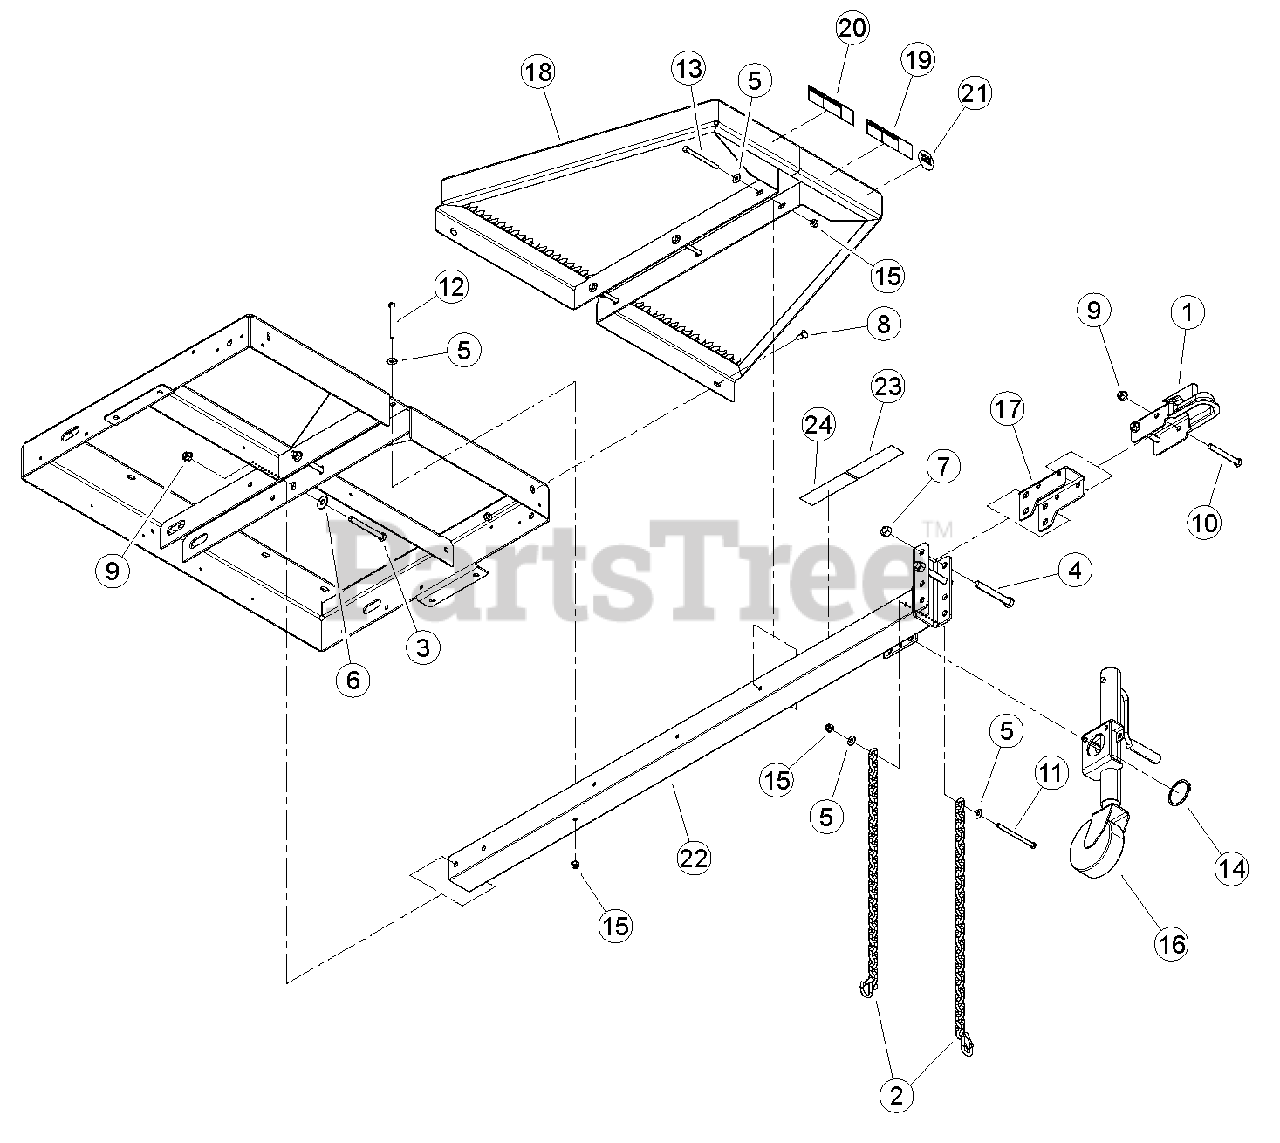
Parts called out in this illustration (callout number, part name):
1	COUPLER, 2 IN
2	CHAIN, SAFETY 5000 LB W/LATCH
3	BOLT, 1/2 X 4-1/2" GR5 HHCS NC ZP
4	BOLT, 5/8 X 4-1/2 HEX HD G5 ZP
5	WASHER, 3/8" FLAT ZP
6	WASHER, 1/2" FLAT ZP
7	NUT, 5/8" CENTERLOCK ZP GR5
8	BOLT, 3/8 X 1" GR5 CRG NC ZP
9	NUT, 1/2-13 NYLOCK FLANGE
10	BOLT, 1/2 X 4 HEX CPS G5 ZP
11	BOLT, 3/8 X 5" GR5 HEX CPS ZP
12	BOLT, 3/8 X 4" HHCS GR5 NC ZP
13	BOLT, 3/8 X 4-1/2" HHCS GR5 NC ZP
14	SNAP RING, 2-1/2 EXTERNAL
15	NUT, 3/8-16 NYLOCK FLANGE
16	JACK, PIVOTING W/ SWIVEL CASTOR
17	MOUNT, COUPLER
18	ASSEMBLY, STORAGE HITCH
19	DECAL, TRAILER ELECTRICAL
20	DECAL, CHECK WHEELS
21	DECAL, NATM COMPLIANCE
22	ASSEMBLY, DL HITCH
23	DECAL, SAFETY CHAINS
24	DECAL, SAFE COUPLING
